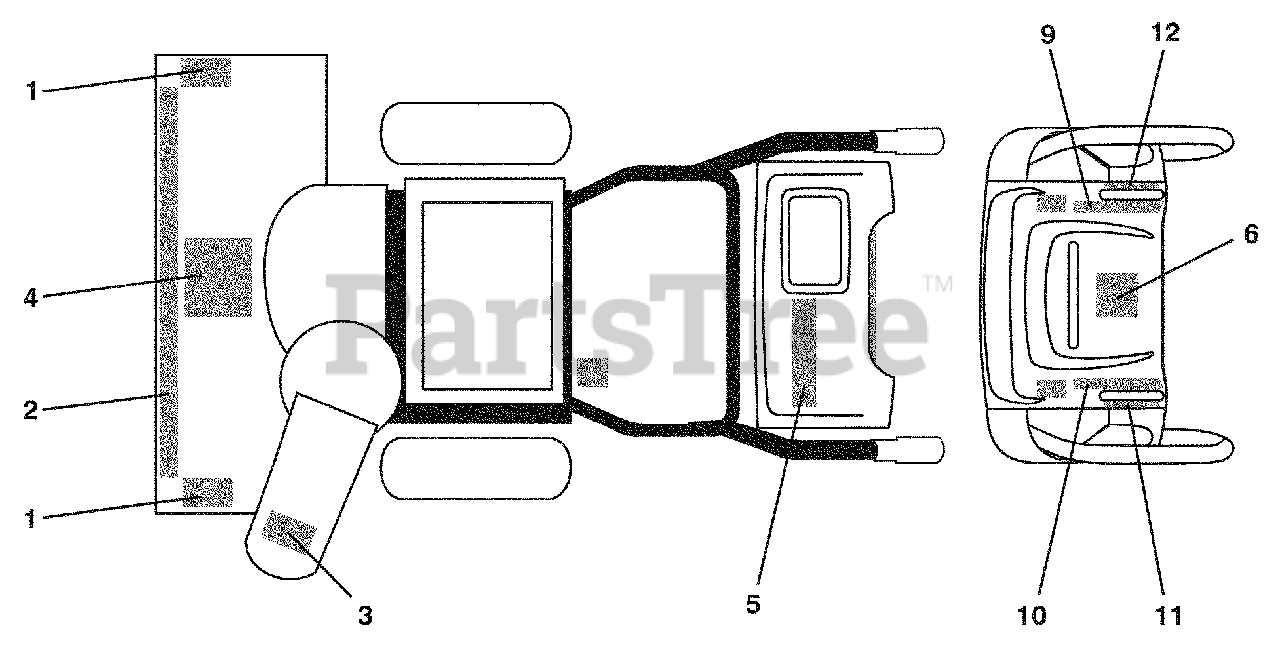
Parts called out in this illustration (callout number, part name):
1	DECAL, DANGER
2	DECAL, HUSQVARNA
3	DECAL, DANGER, DEFLECTOR
4	DECAL, DANGER
5	DECAL, HUSQVARNA, 1130S-XLS
6	DECAL, INSTRUCTION
9	DECAL, AUGER SAFETY
10	DECAL, SPEED CONTROL
11	DECAL, LH TRIGGER
12	DECAL, RH TRIGGER
